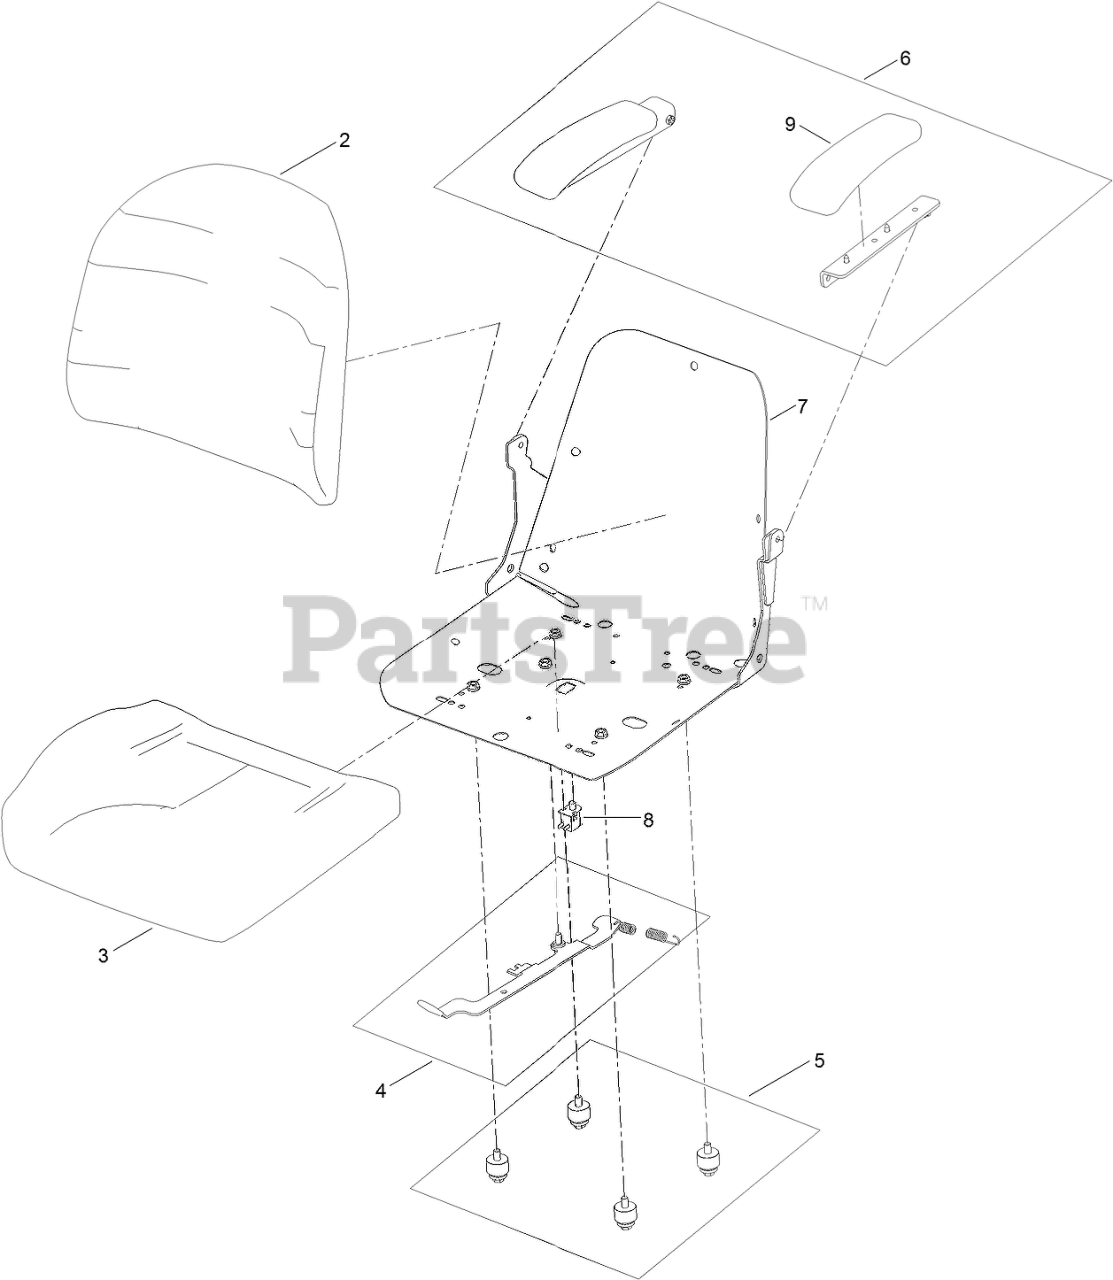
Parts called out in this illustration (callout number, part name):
2	ASM-SEAT BACK
3	ASM-SEAT CUSHION
4	TRACK ASM
5	BUSHING ASM
6	ARMREST KIT
8	SWITCH-BAIL
9	CUSHION-REST, ARM
